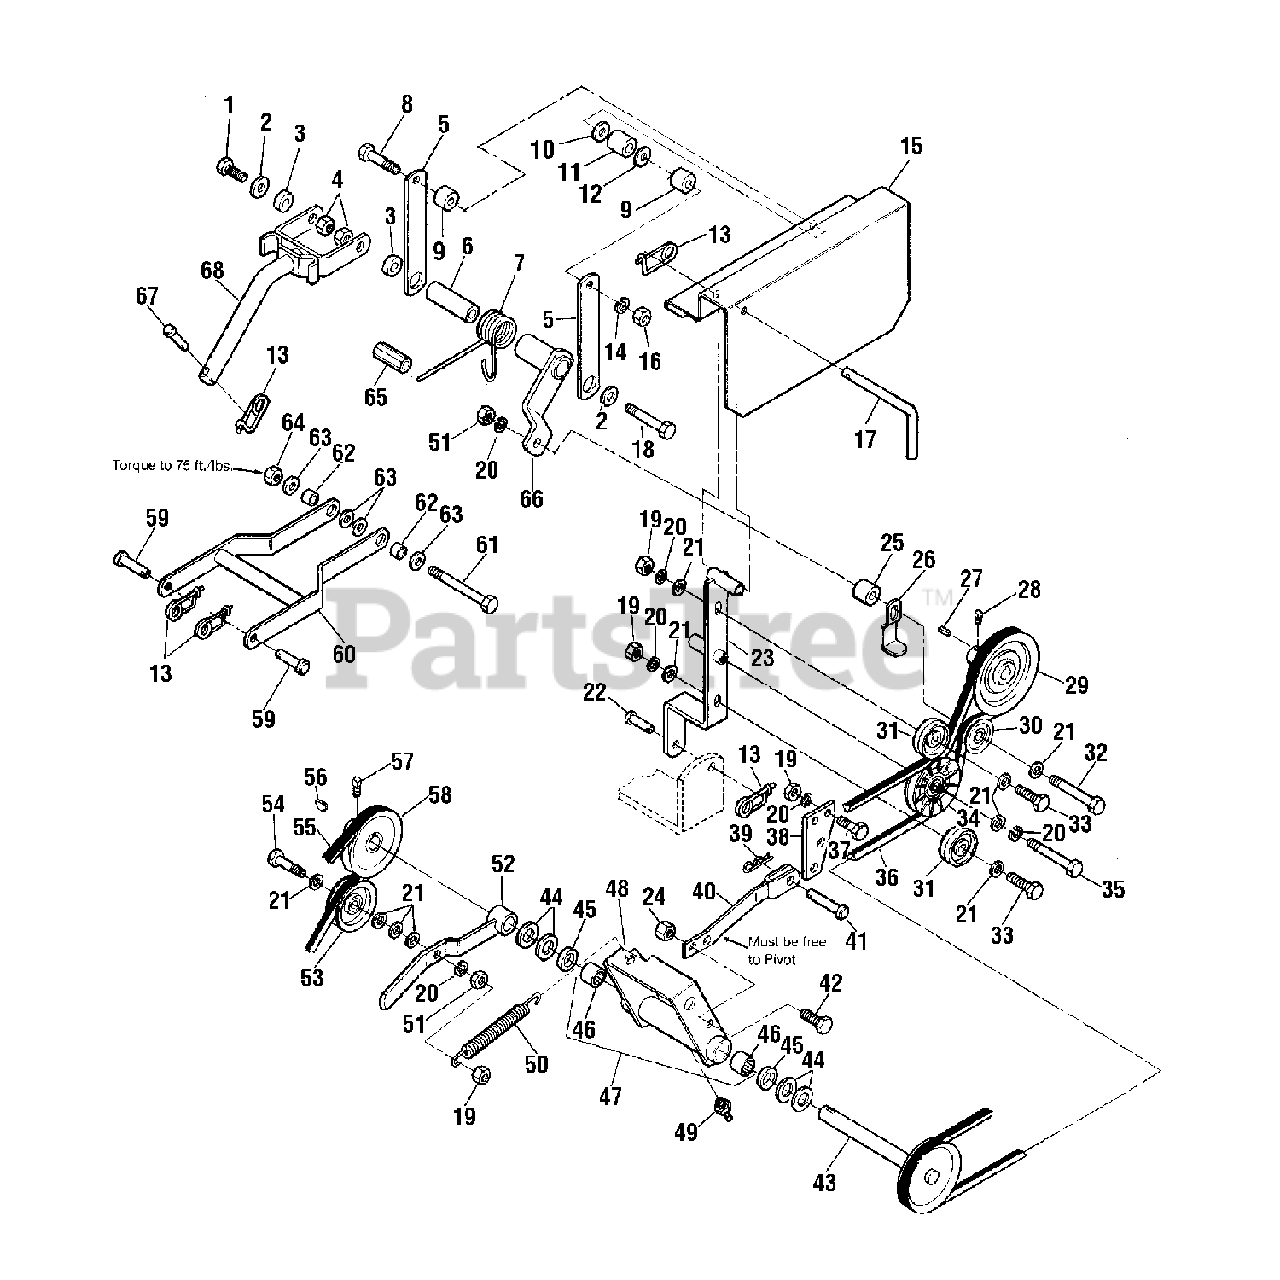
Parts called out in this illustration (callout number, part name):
1	CAPSCREW, Hex Head, 7/16-14 x 1-1/4
2	WASHER, 3/8
4	LOCKNUT, Flange, 7/16-14
7	SPRING, Torsion
8	CAPSCREW, Hex Head, 5/16-18 x 2-3/4
10	WASHER, Nylon
11	BUSHING
12	WASHER, 5/16
13	RETAINER PIN
14	LOCKWASHER, 5/16
15	GUARD, Belt
16	NUT, Hex, 5/16-18
18	CAPSCREW, Hex Head, 7/16-14 x 3-1/2
19	NUT, Hex, 3/8-16
20	LOCKWASHER, 3/8
21	WASHER, 3/8
23	ARM SUPPORT ASSEMBLY
24	NUT, Hex, Centerlock, 5/16-18
26	GUARD, Spring
28	SETSCREW, 3/8-16 x 1/2
30	PULLEY, Idler
31	PULLEY, Idler
32	CAPSCREW, Hex Head, 3/8-16 x 2-3/4
33	CAPSCREW, Hex Head, 3/8-16 x 1-3/4
34	PULLEY, Idler
35	CAPSCREW, Hex Head, 3/8-16 x 1-1/4
37	CAPSCREW, Hex Head, 3/8-16 x 1
38	ANCHOR, Jackshaft
40	ANCHOR ASSEMBLY
41	PIN
42	CAPSCREW, Hex Head, 5/16-18 x 1
43	PULLEY ASSEMBLY
44	WASHER, 3/4
46	BEARING
47	CLEVIS ASSEMBLY, w/Bearings (incl. Ref. Nos. 48 & 46)
49	FITTING, Lube
50	SPRING, Extension
51	NUT, Hex, Centerlock, 3/8-16
52	ARM ASSEMBLY, Idler
53	PULLEY, Idler
54	CAPSCREW, Hex Head, 3/8-16 x 2
57	SETSCREW, 5/16-18
58	PULLEY ASSEMBLY
60	FRAME ASSEMBLY
61	CAPSCREW, Hex Head, 1/2-13 x 5
63	WASHER, 1/2
64	LOCKNUT, 1/2-13
65	ANCHOR, Spring
66	LEVER ASSEMBLY, Clutch
67	PIN
68	LIFT ASSEMBLY
